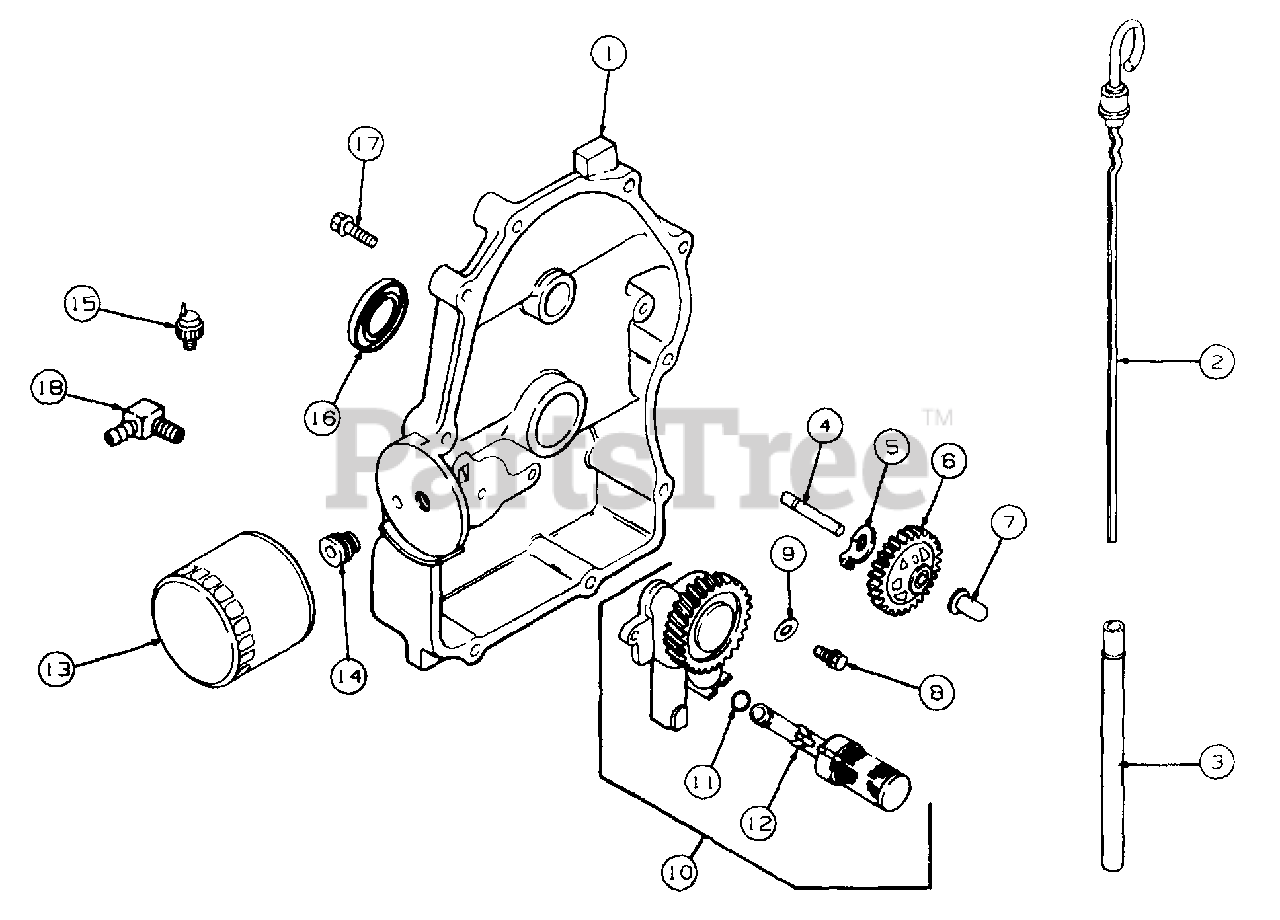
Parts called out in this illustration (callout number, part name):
1	Plate, Closure
2	Dipstick
3	Tube, Dipstick
4	Shaft, Governor Gear
5	Tab, Locking
6	Governor Gear Assembly
7	Pin, Governor Regulating
8	Screw, Hex Flange, M6 x 1.0 x 25
9	Washer, Plain
10	Oil Pump Assembly
11	O-Ring, Oil Pick-up
12	Pick-Up, Oil
13	Filter, Oil
14	Nipple, Oil Filter
15	Switch, Pressure
16	Seal, Oil (PTO End)
17	Screw, Closure Plate M8 x 1.25 x 45
18	Connector, 90° Hose
